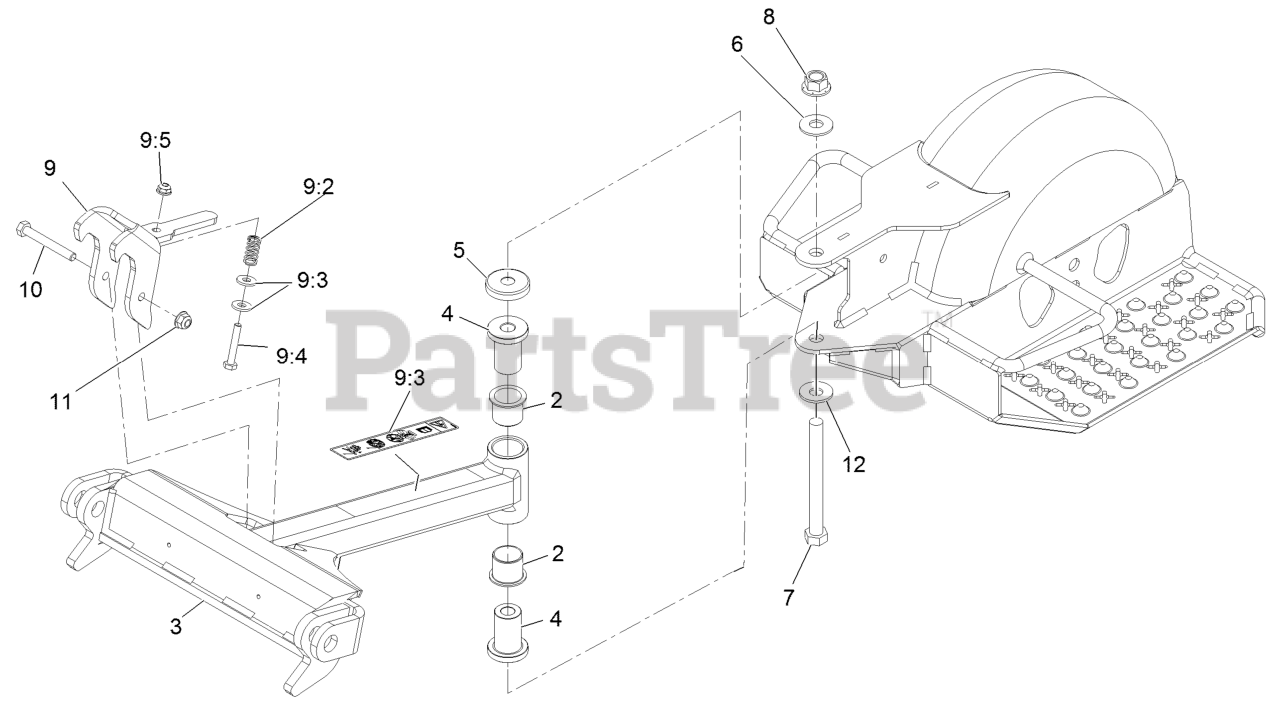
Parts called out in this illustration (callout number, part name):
2	BUSHING-PIVOT
3	DECAL-SULKY HAZARD
4	SPACER, PIVOT
5	COVER, DUST
6	WASHER-BELLEVILLE
7	SCREW-HH
8	Nut-Lock 1/2-13
9	TRANSPORT LATCH ASM
9:2	SPRING, COMPRESSION
9:3	WASHER-FLAT
9:4	SCREW-HH
10	SCREW-HH
11	NUT-HF, NI
12	WASHER-SPRING
